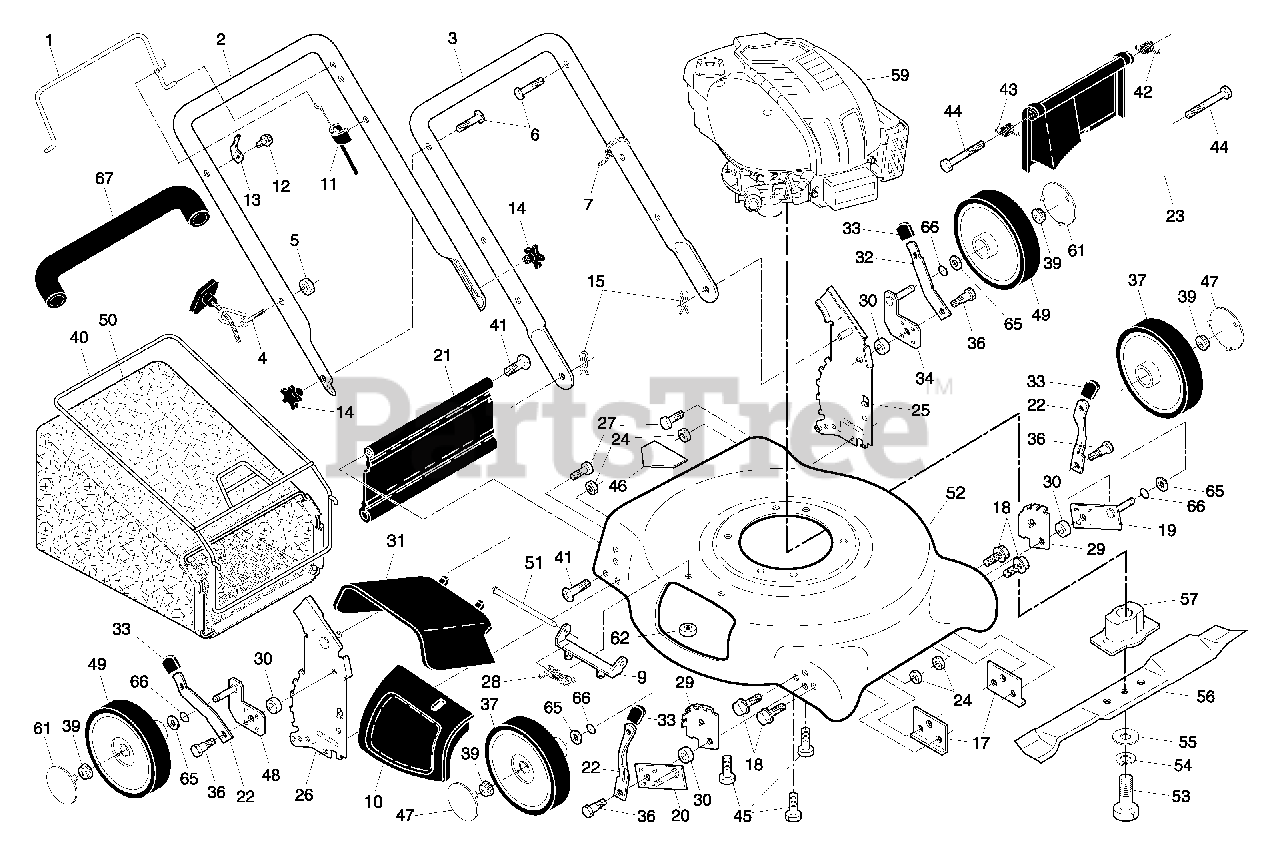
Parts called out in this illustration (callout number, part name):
1	Control Bar
2	Upper Handle
3	Lower Handle
4	Rope Guide
5	Nut, Hex 1/4-20
6	Handle Bolt
7	Wire Tie
9	Bracket, Housing
10	Mulcher Door
11	Engine Zone Control Cable
12	Hex Washer Head Screw
13	Up-Stop Bracket
14	Handle Knob
15	Hairpin Cotter
17	Support Bracket
19	Axle Arm Assembly, Front, LH
20	Axle Arm Assembly, Front, RH
21	Rear Skirt
22	Selector Spring, Front
23	Rear Door Kit
24	Locknut, Hex 5/16-18
25	Handle Bracket Assembly, LH
26	Handle Bracket Assembly, RH
27	Screw 1/4-20 x 3/8
28	Hinge Spring
29	Wheel Adjusting Bracket, Front
31	Clip-on Discharge Guard
32	Selector Spring, Rear
33	Selector Knob
34	Axle Arm Assembly, Rear, LH
36	Shoulder Bolt 5/16-18
37	Wheel Assembly, Front
39	Flanged Locknut
40	Frame, Grassbag
41	Hinge Screw
42	Spring, Rear Door, LH
43	Spring, Rear Door, RH
45	Hex Head Thread Rolling Screw 3/8-16 x 1
46	Danger Decal
47	Hubcap, Front Wheel
48	Axle Arm Assembly, Rear, RH
49	Wheel Assembly, Rear
50	Grassbag
52	Kit, Lawn Mower Housing
53	Hex Head Screw 3/8-24 x 1-3/8 Grade 8
54	Helical Lockwasher
55	Hardened Washer
57	Blade Adapter
61	Hubcap, Rear Wheel
62	Locknut, Hex 1/4-20
65	Washer, Flat 3/8
66	O-Ring
67	Grip, Foam
